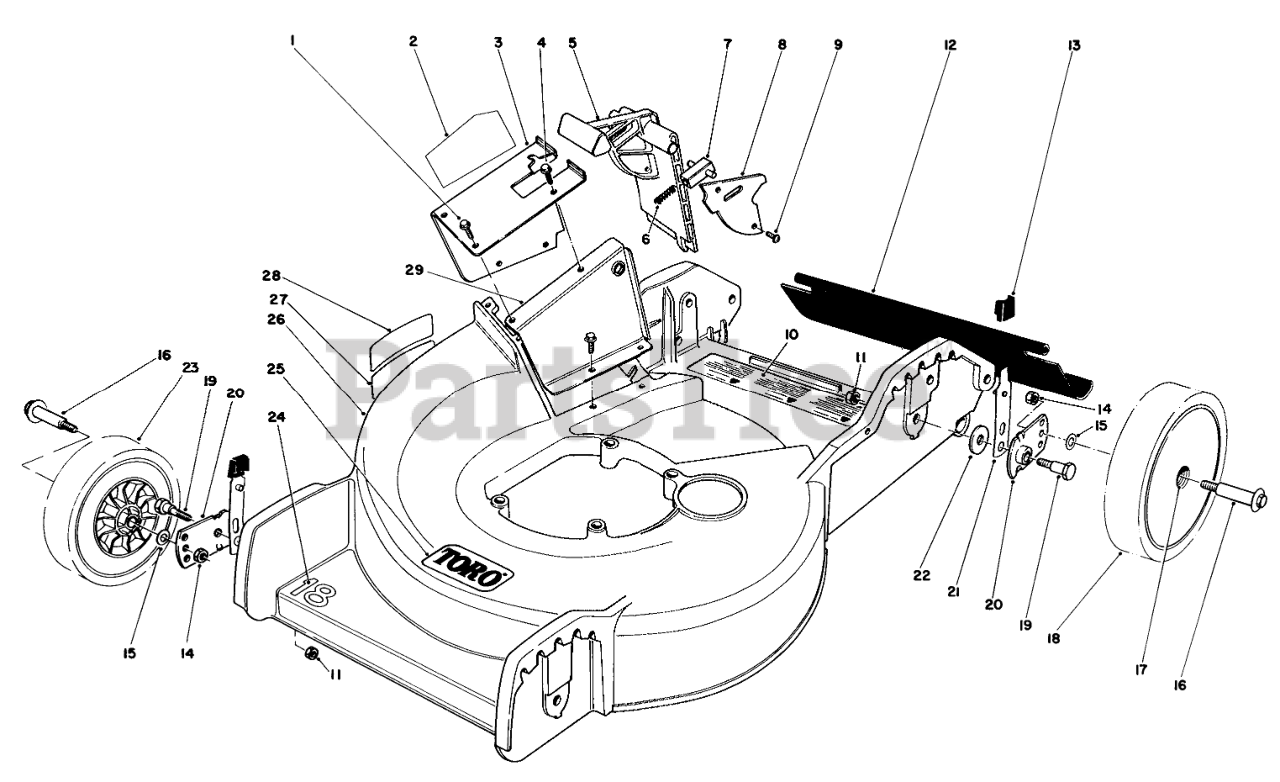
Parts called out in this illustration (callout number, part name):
1	Screw Thread Forming (Incl. Ref. #2)
2	Decal-Danger
3	Tunnel-Outer (Incl. Ref. #2)
4	SCREW
5	Door Mulching
6	SPRING-COMPRESSION, LATCH
7	Door Latch
8	Cover Door
10	Decal-Danger
11	NUT-LOCK, NI
12	SHIELD - TRAILING
13	KNOB-ARM
14	Nut
15	WASHER
16	BOLT-WHEEL
17	BUSHING
18	Wheel & Tire Assembly (Incl. Ref. #17)
19	PIVOT SCREW
20	PIVOT ARM ASSY
21	SPRING ARM ASM
22	PIVOT WASHER
23	Wheel & Tire Assembly (Incl. Ref. #17)
24	Decal
25	Decal Tow
26	Housing
27	Decal-Step Pad
28	STEP PAD DECAL
29	Tunnel-Inner
